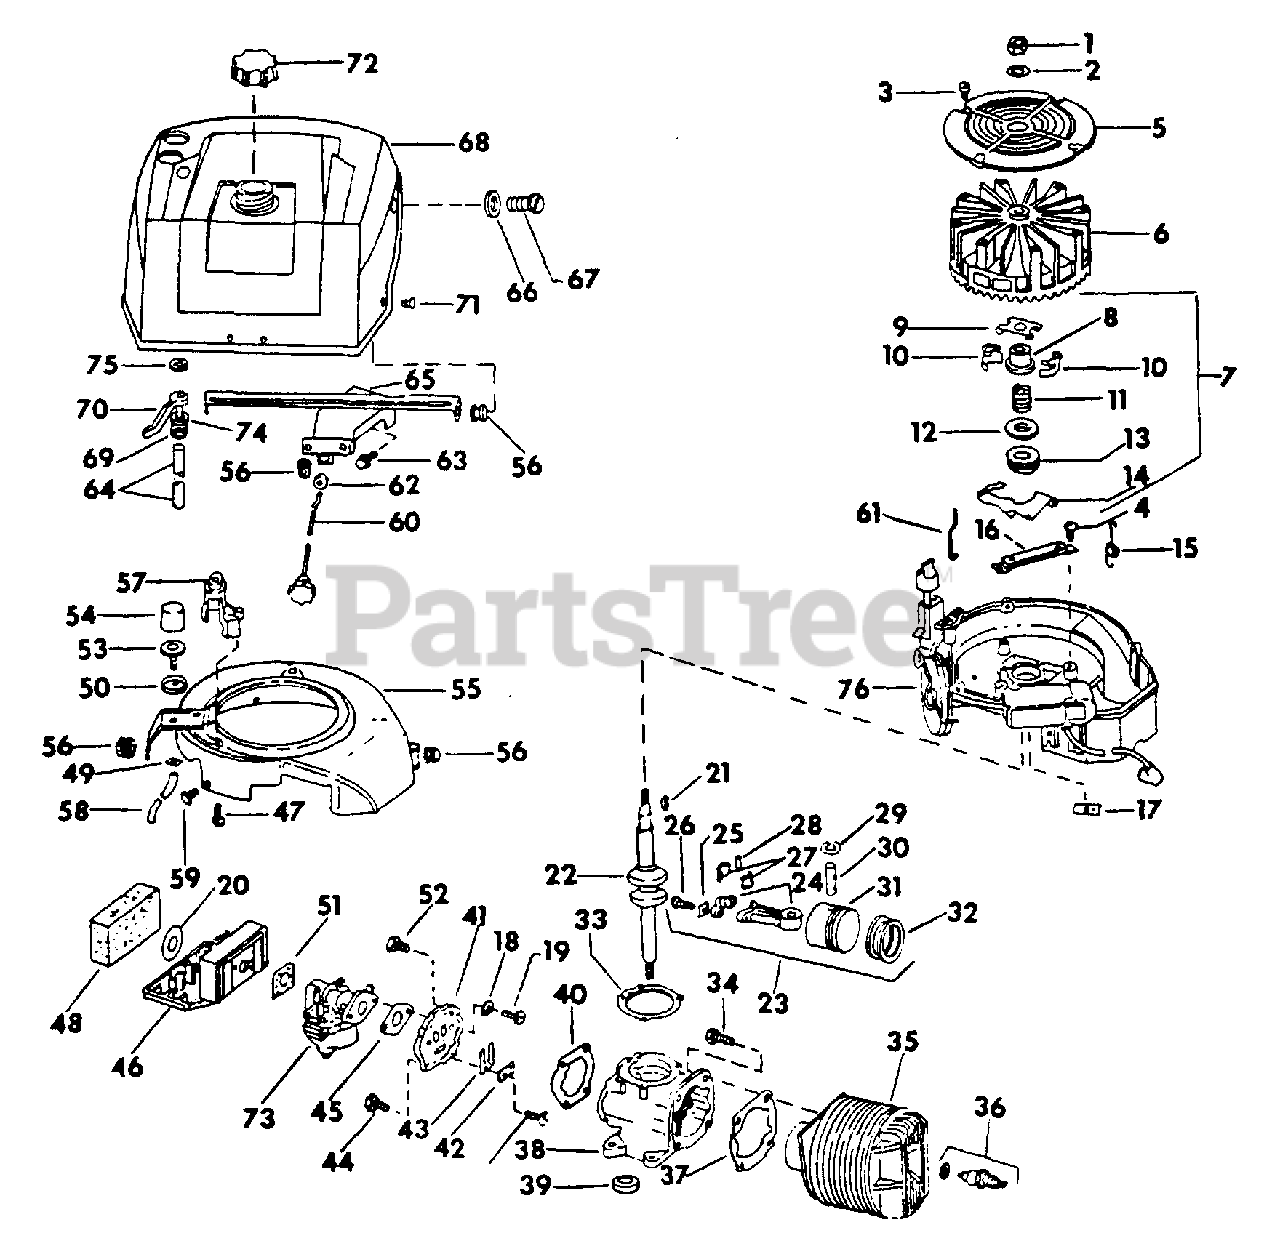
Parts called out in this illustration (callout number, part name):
1	NUT, 7/16-20 HEX.
2	WASHER, 7/16 ZND INT TOOTH LOCK
3	SCREW, 10-24 X 1/2 TRUSS-HD REC TAP.
4	SCREW, 5/16-18 X 1-3/8 ZND HEX-HD CAP
5	SCREEN, FLYWHEEL
7	GOVERNOR ASSY
8	COLLAR, GOVERNOR
9	YOKE, GOVERNOR
10	WEIGHT, GOVERNOR
11	SPRING, GOVERNOR
12	WASHER, THRUST
13	COLLAR, THRUST
14	LEVER, GOVERNOR
15	SPRING, VARIABLE SPEED
16	BRACKET, GOVERNOR LEVER
21	KEY, CRANKSHAFT
23	PISTON & CONNECTING ROD ASSY
24	ROD ASSY, CONNECTING
25	LOCKPLATE, SCREW
26	SCREW, CONNECTING ROD
27	LINER, CONNECTING ROD
28	BEARING SET, NEEDLE
29	RING, RETAINING
32	RING SET, PISTON -2 RINGS
33	GASKET, CRANKCASE TO ARM PLATE .010
34	SCREW, CYL TO CRANKCASE
36	SPARK PLUG & GASKET
37	GASKET, CYL TO CRANKCASE
38	CRANKCASE & SEAL ASSY
40	GASKET, REED PLATE
41	REED PLATE ASSY
42	PLATE, BACKUP
44	SCREW, HH REED PLATE TO CRANKCASE
45	GASKET, CARBURETOR
46	FILTER ASSY, AIR
48	ELEMENT, FILTER
52	SCREW, HH REED PLATE TO CRANKCASE
54	BULB, PRIMER
55	BAFFLE ASSY AIR
57	BRACKET & EYELET
61	ROD, GOVERNOR
65	BRACKET, SHROUD
68	SHROUD, TANK & VALVE ASSY
69	CLIP, SPRING
71	SCREW, COVER MTG
73	CARBURETOR ASSY
76	MAGNETO ASSY
